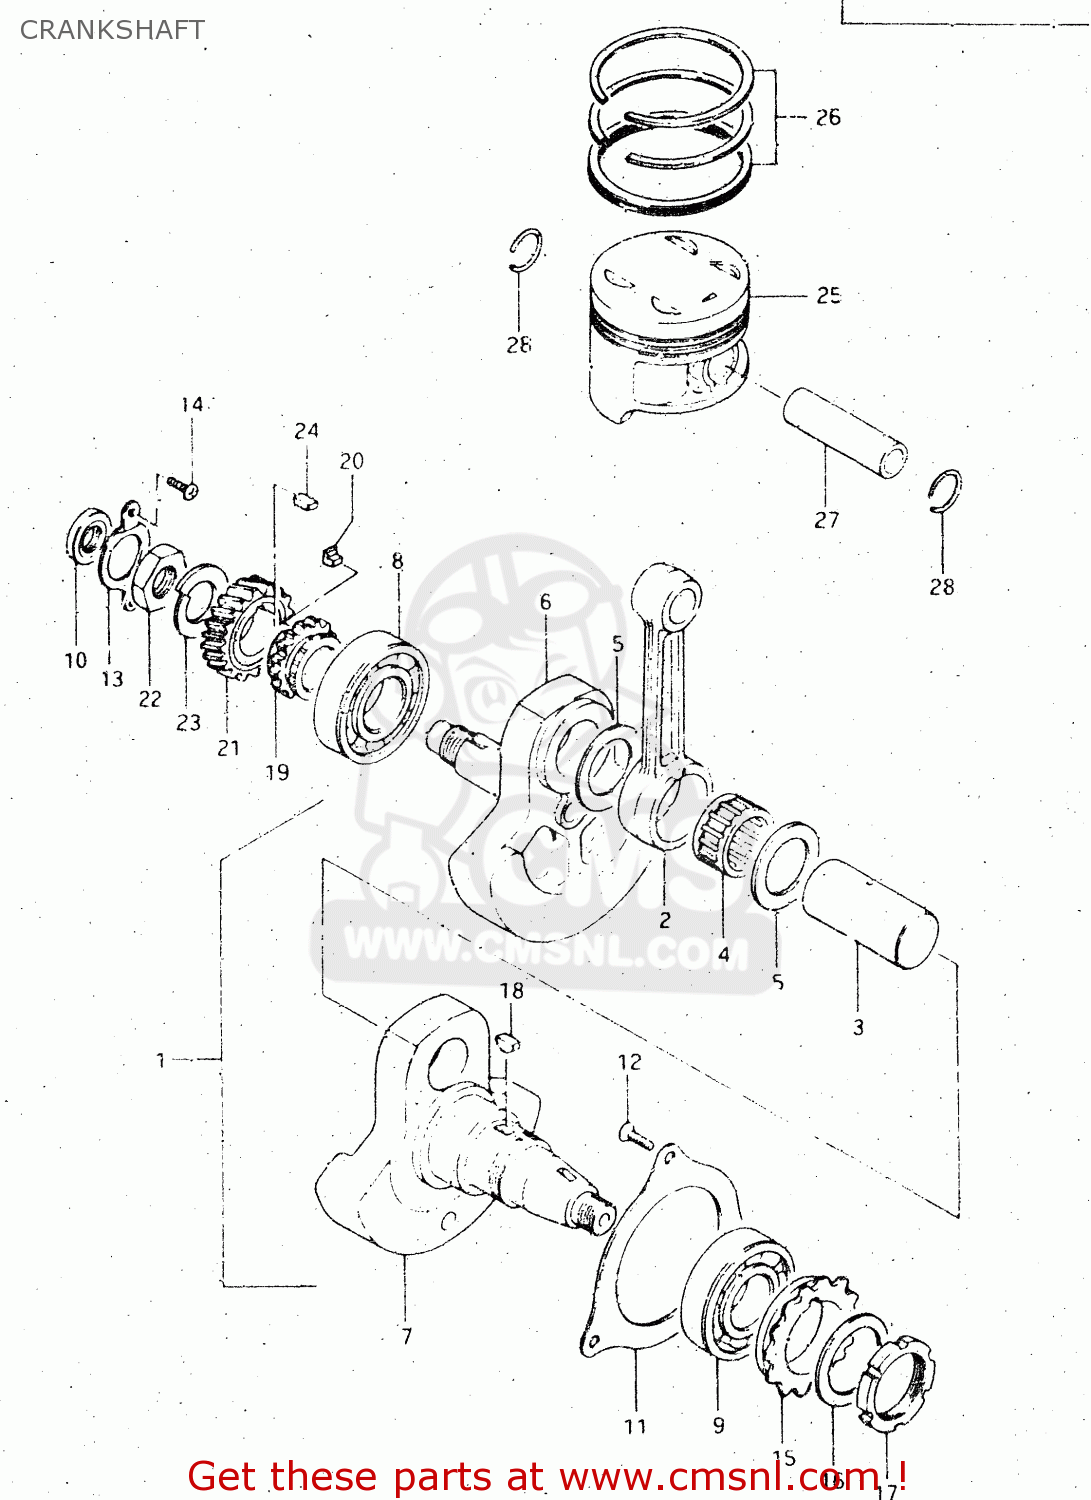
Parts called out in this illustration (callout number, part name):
1	CRANKSHAFT ASSEMBLY
2	ROD,CONNECTING
3	PIN,CRANK
4	BEARING(35X44X26)
5	WASHER(35X55X1)
6	CRANKSHAFT
7	CRANKSHAFT,LEFT
8	BEARING(35X80X21)
9	BEARING
10	SEAL,OIL(16X30X6)
11	RETAINER,CRANKSHAFT BEARING,L
12	SCREW
13	RETAINER,CRANKSHAFT BEARING,R
14	SCREW
15	SPROCKET,BALANCER DRIVE
16	WASHER
17	NUT,FLYWHEEL
18	KEY
19	SPROCKET,CAM CHAIN DRIVE
20	KEY,SPROCKET
21	GEAR,PRIMARY DRIVE
22	NUT (20MM)
23	WASHER
24	KEY
25	PISTON
26	RING SET,PISTON
27	PISTON PIN
28	RING,SNAP
